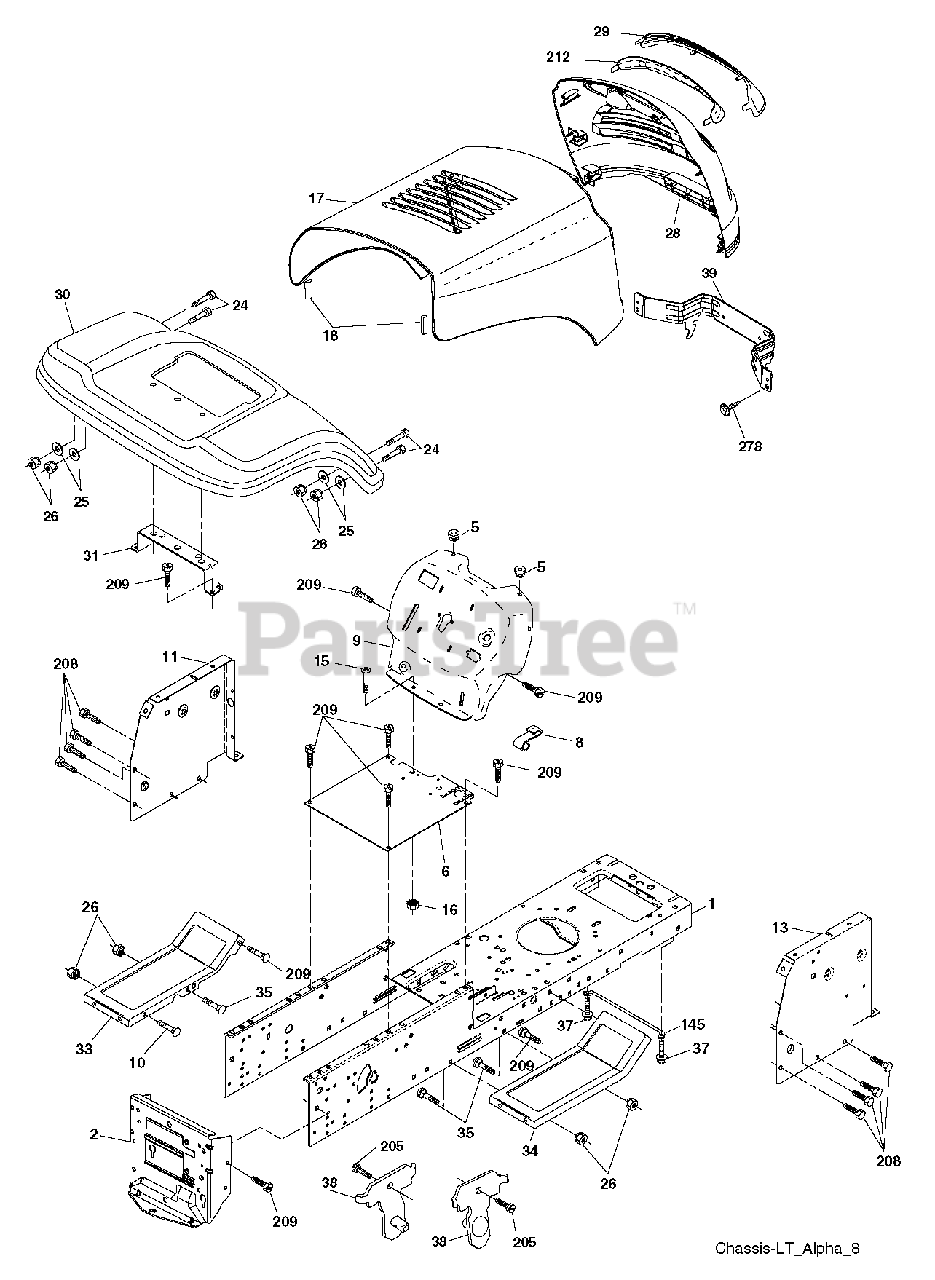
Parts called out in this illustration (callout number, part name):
1	CHASSIS
2	DRAWBAR, 12GA
5	BUMPER.RUBBER.HOOD
8	CLIP RETAINER
10	BOLT D
11	PANEL.DASH.LH.LTX
16	NUT
17	HOOD.PNT.STEEL.ALPHA.LT.667
18	BUMPER.HOOD.LARGE.1.75"
25	WASHER
26	NUT
28	GRILLE.ASM.ALPHA
29	LENS.ALPHA.BAR.LT
30	FENDER.PNT.LT.W/SFT.W/OCUP.667
31	BRACKET FENDER
33	FOOTREST.PNT.LH.MS667
34	FOOTREST.PNT.RH.MS667
38	BRACKET.ASM.PIVOT.MOWER.REAR
39	BRACKET.PIVOT.ALPHA.LT
145	ROD.PIVOT.HOOD
208	SCREW 3/8-16X1/2
209	SCREW, 3/8-16X3/4
212	INSERT.ALPHA.REFLECTIVE.LT.
278	SCREW.#10 X 0.750.BOS THREAD
